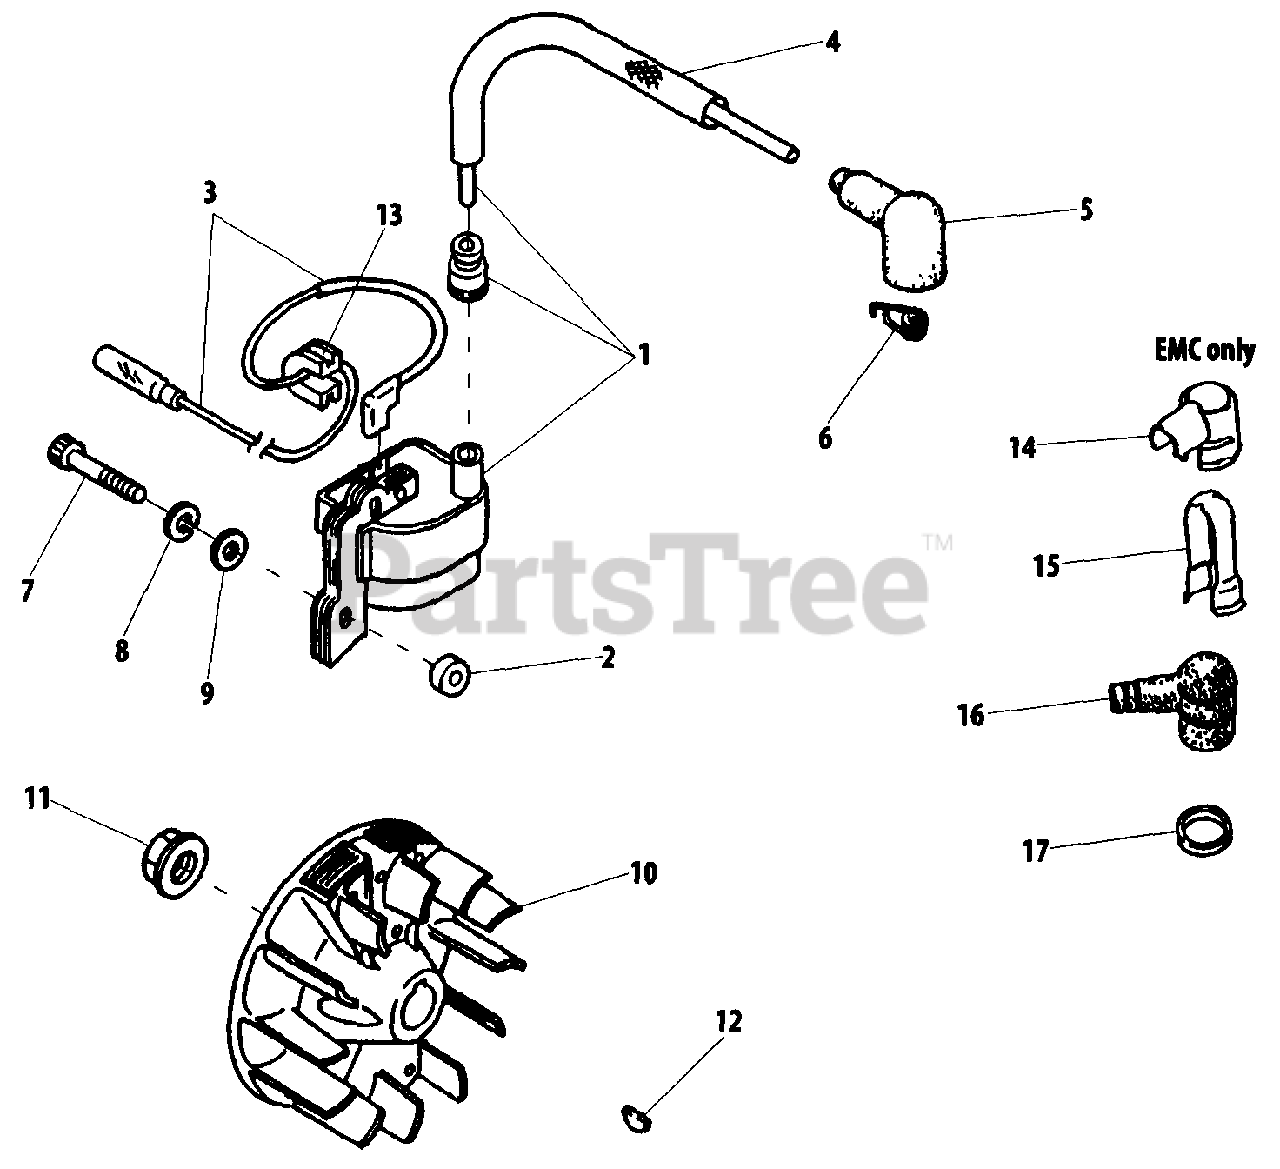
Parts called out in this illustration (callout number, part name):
1	IGNITION COIL ASSY
2	INSULATOR
4	TUBE
5	CAP, SPARK PLUG
6	TERMINAL, SPARK PLUG CAP
7	SCREW - 4X26
8	LOCKWASHER - 4
9	WASHER - 4
10	FLYWHEEL
11	NUT - 8
12	KEY - 3X10
13	GROMMET
14	CAP, SPARK PLUG
15	SHIELD
16	CAP, SPARK PLUG
17	SEAL, DUST
